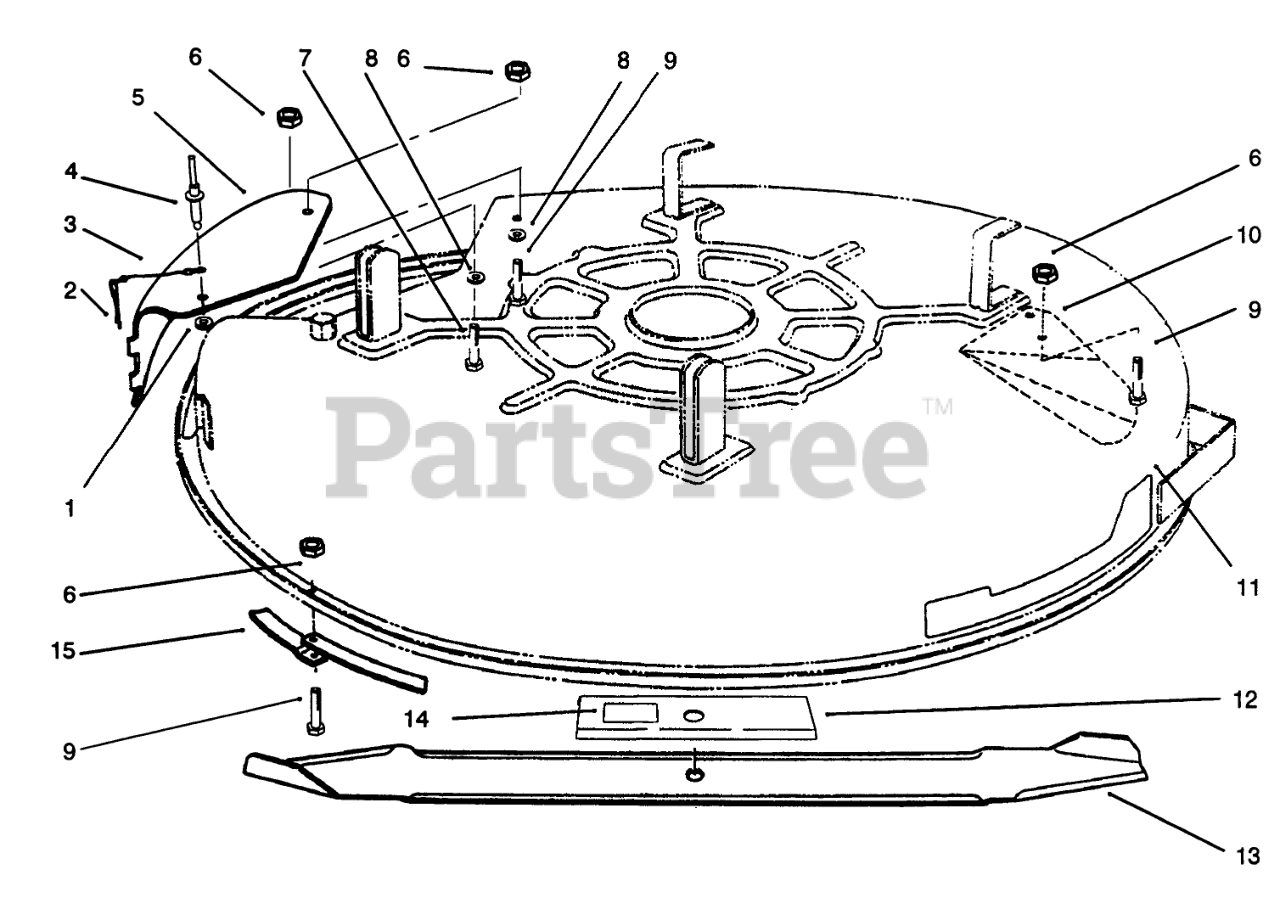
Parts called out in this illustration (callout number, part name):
1	WASHER-PLAIN
2	PIN-LOCKING, CHUTE
3	LANYARD
4	RIVET-BLIND
5	Discharge Cover Assembly (Incl. Ref. #1-4)
6	NUT-LOCK, NI
7	SCREW-HH
8	WASHER-PLAIN
9	SCREW-HH
10	Kicker
11	DECAL/RECYCLER 32" BACK
12	Spacer-Blade (Incl. Ref. #14)
13	BLADE-RECYCLER
14	Decal-Danger
15	Ring-Deck
